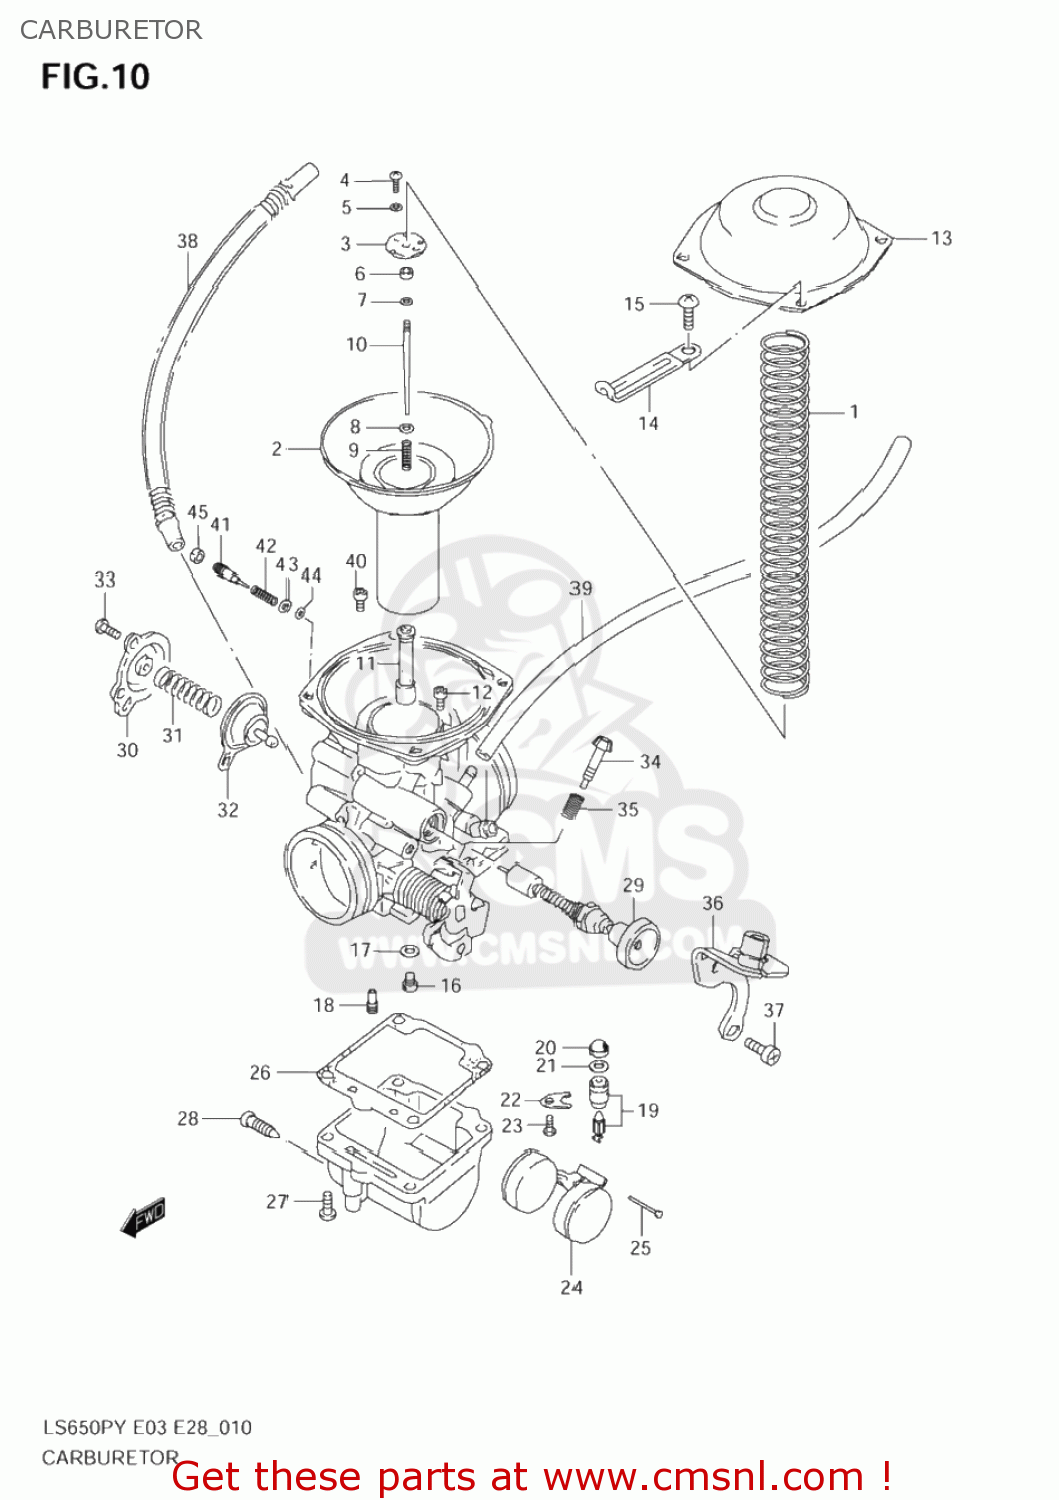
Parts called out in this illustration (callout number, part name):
1	SPRING
2	DIAPHRAGM ASSY
3	PLATE
4	SCREW
5	WASHER,LOCK
6	RING
7	CLIP,NEEDLE
8	WASHER
9	SPRING
10	NEEDLE,JET(5C17)
11	JET,NEEDLE(X-7M)
12	JET(45)
13	COVER
14	CLAMP(L:80 T:1.0)
15	SCREW
16	JET,MAIN(145)
17	WASHER
18	JET,PILOT(52.5)
19	VALVE ASSEMBLY,NEEDLE
20	FILTER
21	O-RING,NEEDLE VALVE
22	PLATE
23	SCREW 4X6
24	FLOAT
25	PIN,FLOAT
26	GASKET,FLOAT CAHMBER (NAS)
27	SCREW
28	SCREW,DRAIN
29	PLUNGER ASSEMBLY
30	COVER
31	SPRING
32	DIAPHRAGM ASSY
33	SCREW
34	ADJUSTER
35	SPRING
36	BRACKET ASSY
37	SCREW
38	HOSE ASSEMBLY
39	HOSE(5X8.2X600)
40	JET,PILOT(230)
41	SCREW,AIR
42	SPRING
43	WASHER
44	O RING,PILOT AIR SCREW
45	PLUG
